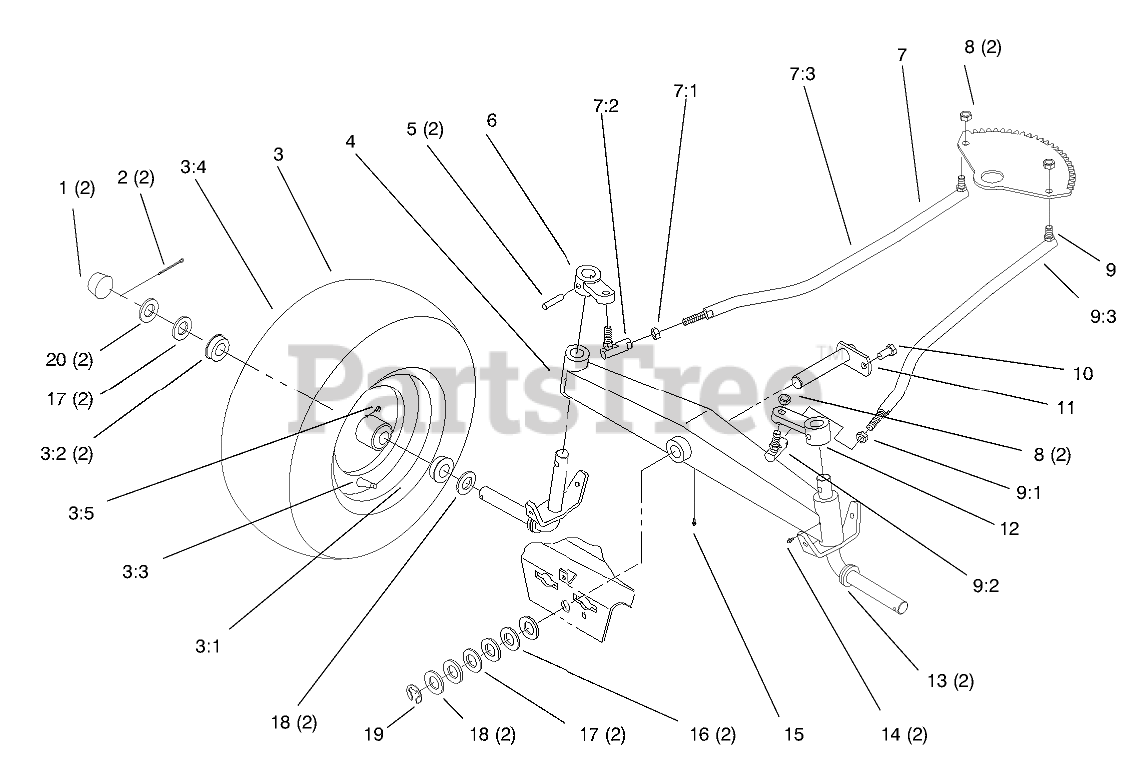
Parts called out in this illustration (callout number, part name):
1	CAP-HUB
2	PIN-COTTER
3	FRONT WHEEL ASM
3:1	Wheel ASM
3:2	BEARING-WHEEL
3:3	VALVE
3:4	Tire (16 x 6.5-8) 2-Ply -2 Wheel Axel
3:5	ZERK-GREASE
4	AXLE-FRONT
6	Arm-Front Spindle
7	LINKAGE-STEERING, RH
7:1	Nut-Hex Jam
7:2	BALL-JOINT
7:3	Ball Link ASM
9	LINKAGE-STEERING, LH
9:1	Nut-Hex Jam
9:2	BALL-JOINT
9:3	Ball Link ASM
10	SCREW-HWH, TAPTITE
11	PIN-AXLE
12	Arm-Front Spindle
13	SPINDLE
14	FITTING-GREASE
15	FITTING-LUBE, 45 DEG
16	Washer
17	WASHER
18	WASHER-SHIM
19	E-RING
20	WASHER-PLAIN
